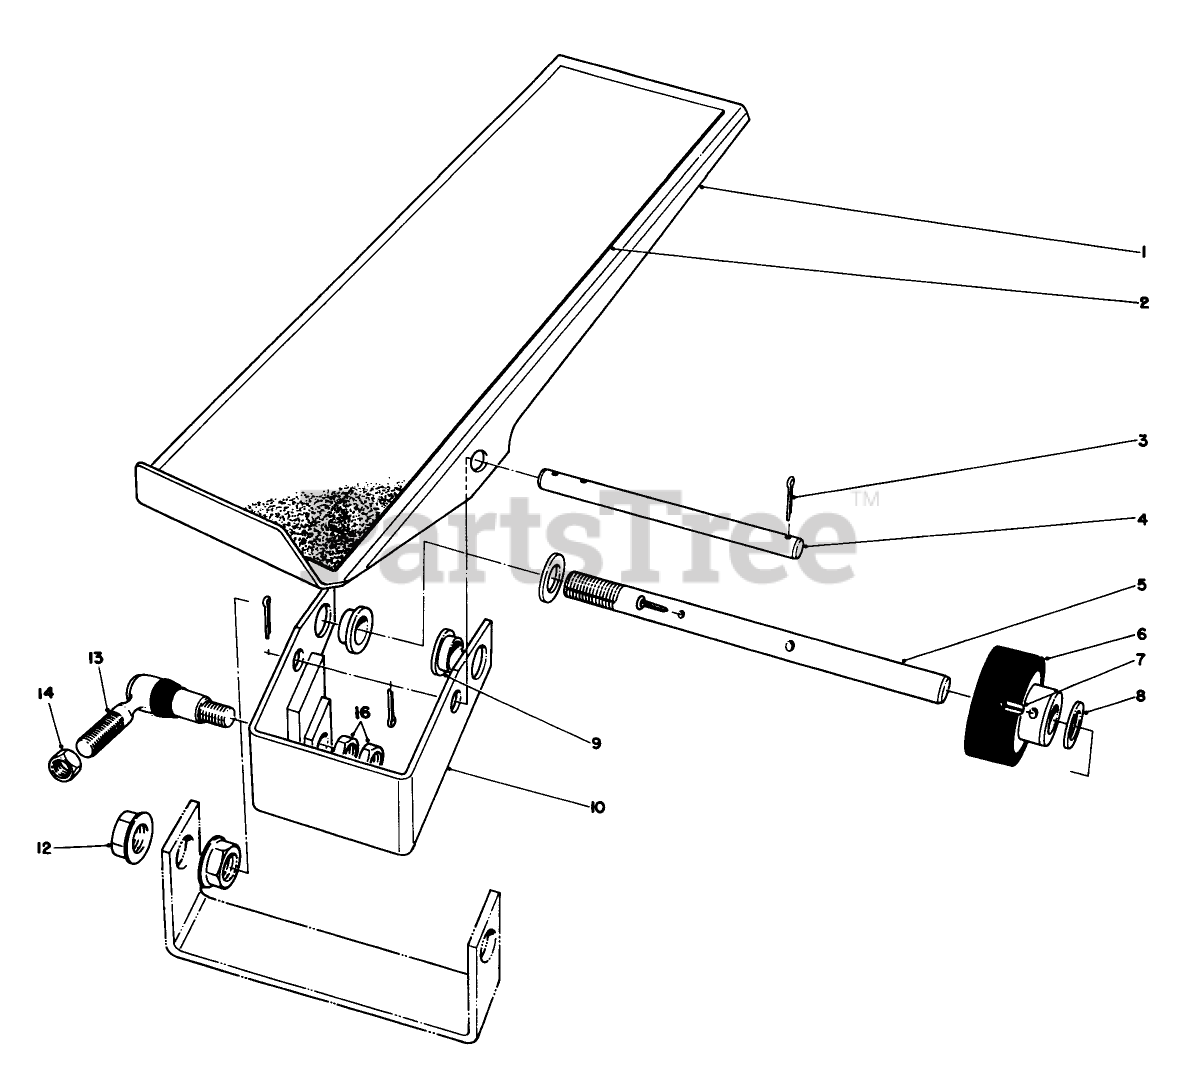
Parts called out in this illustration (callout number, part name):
1	Pedal-Traction
2	TRACTION PEDAL PAD
3	PIN-COTTER
4	PEDAL PIVOT PIN
5	Shaft-Traction Pedal
6	FRICTION WHEEL ASM
7	PIN-ROLL, SLOTTED
8	WASHER-FLAT
9	BUSHING-FLANGE
10	Pivot Bracket Assembly (Incl. Ref. #9)
11	WASHER-LOCK
12	NUT-HHF
13	RH BALL JOINT ASM
14	NUT-JAM
16	NUT-HJ
